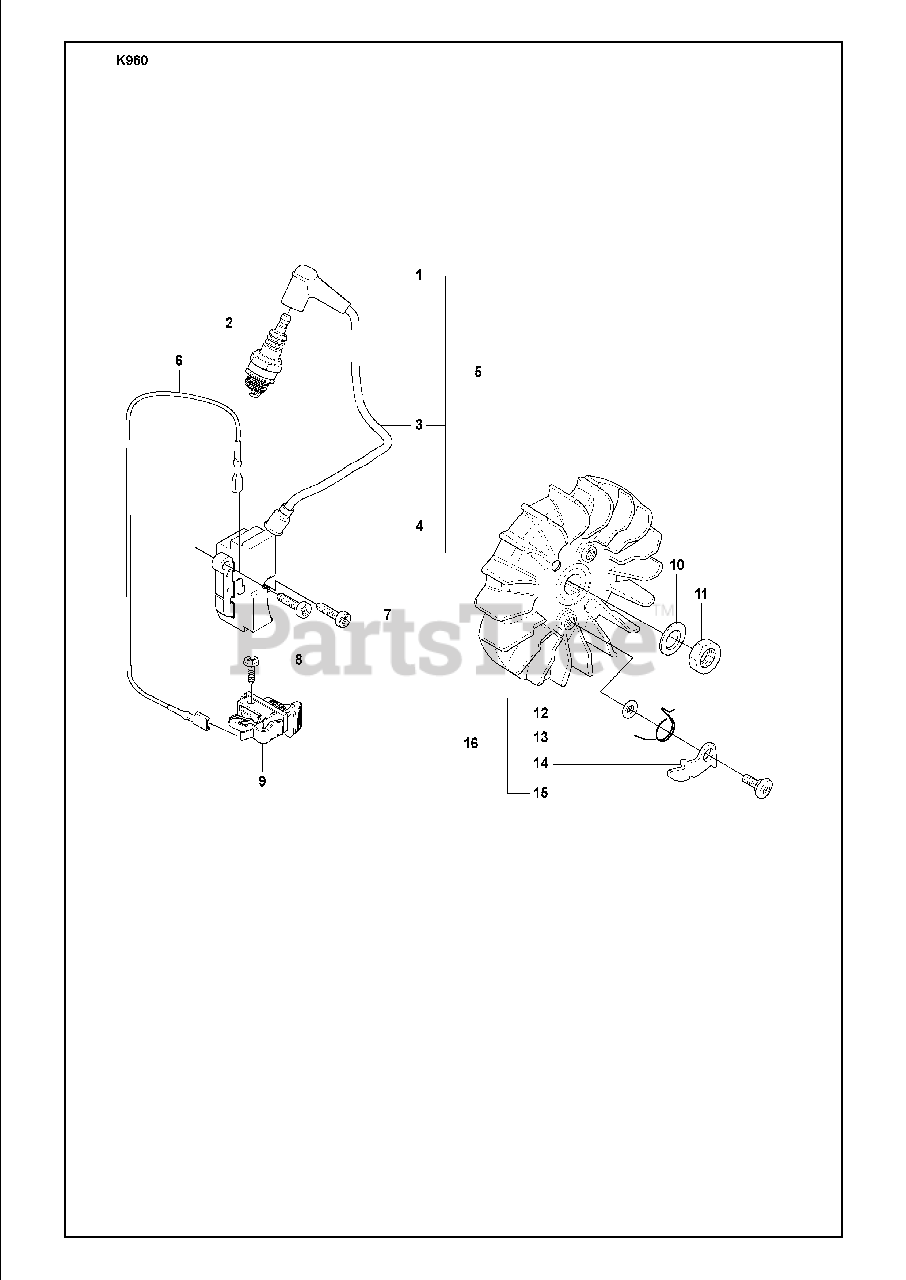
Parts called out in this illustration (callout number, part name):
1	Spark Plug Cap
2	Spark Plug
3	Ignition Cable
4	Insulating Cap
5	Ignition Module
9	Stop Switch
10	Washer Steel
12	Washer Steel
15	Screw
16	Flywheel
